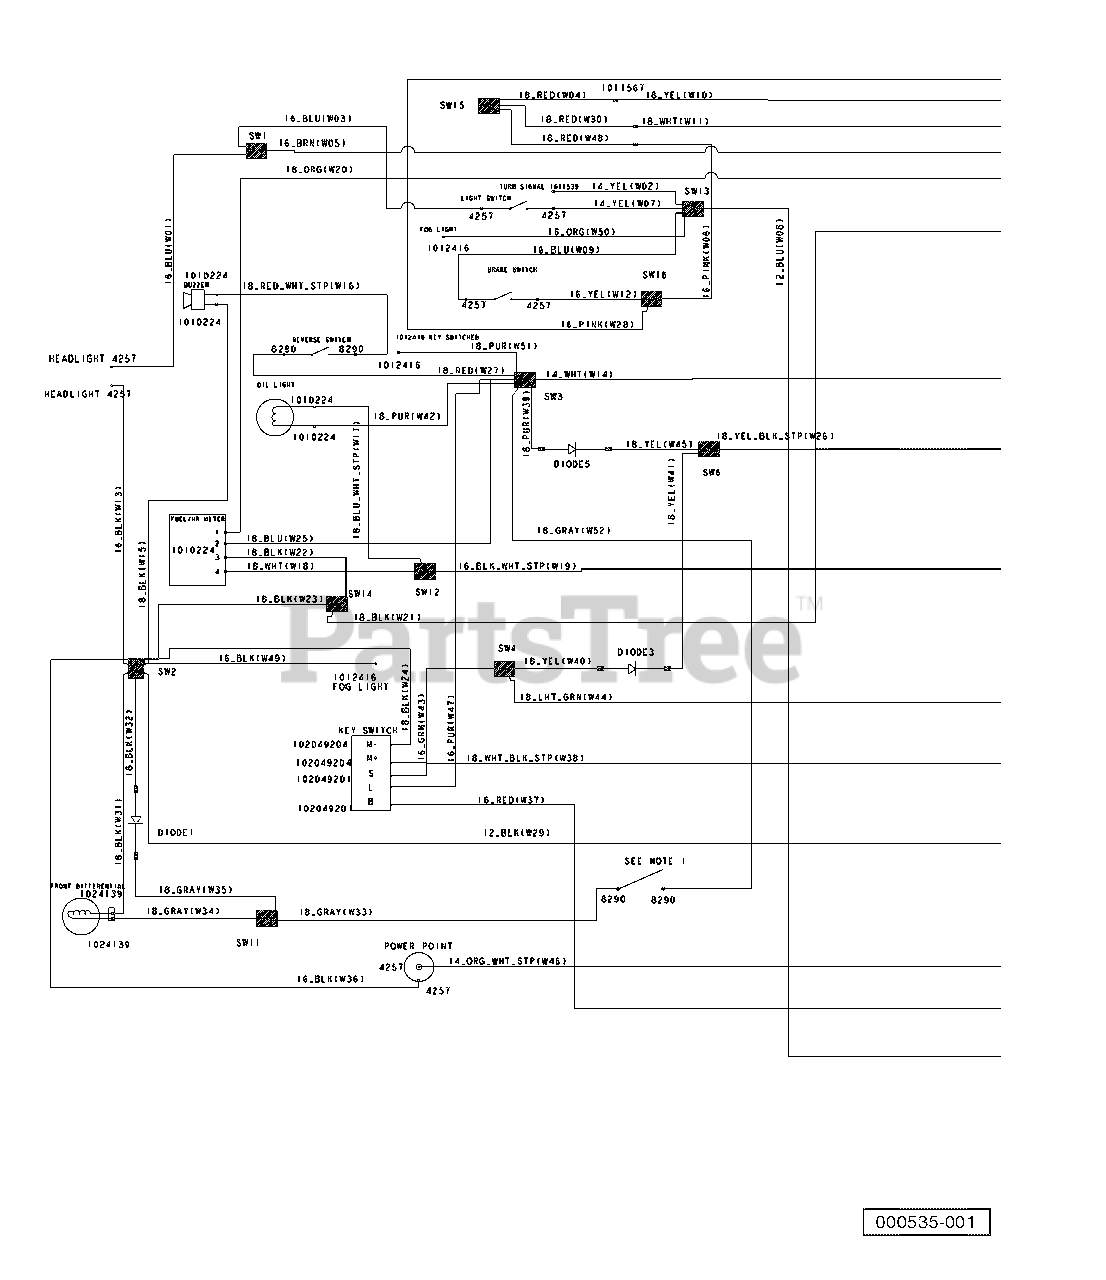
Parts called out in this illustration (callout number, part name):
1	Diode, General Purpose, 6.0a
2	Harness, Restyle Gas, Front
3	Harness, Restyle Gas, Rear
4	Asm, Switch, Limit
